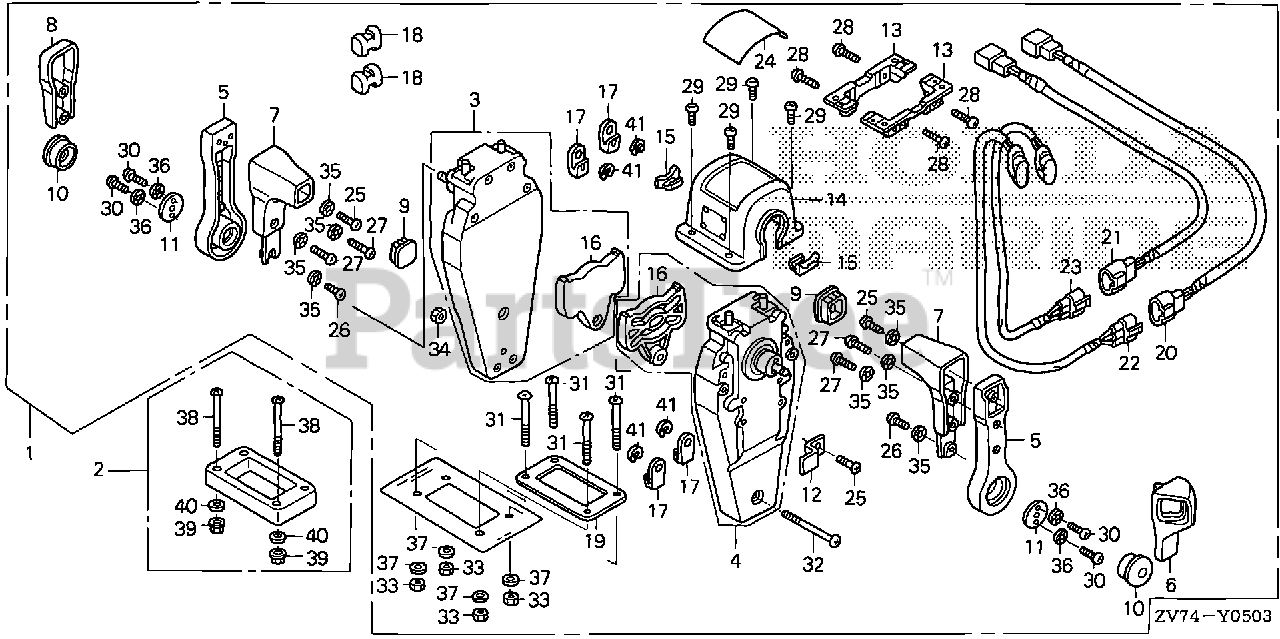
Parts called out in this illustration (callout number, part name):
1	BOX KIT, REMOTE CONTROL (TOP MOUNT DUAL)(L)
2	SPACER KIT, REMOTE CONTROL BOX (TOP MOUNT DUAL)
3	HOUSING ASSY., L. (INNER) (TOP MOUNT)
4	HOUSING ASSY., R. (INNER) (TOP MOUNT)
5	HANDLE, REMOTE CONTROL
6	COVER, R. GRIP
7	GRIP, REMOTE CONTROL HANDLE
8	COVER, DUAL GRIP
9	CAP, GRIP
10	BUTTON, THROTTLE
11	PLATE, HANDLE
12	PLATE, CABLE CLAMP
13	BRACKET, REMOTE CONTROL HOUSING
14	HOUSING, DUAL REMOTE CONTROL BOX
15	HOUSING, LEAD
16	PLATE, DWELL
17	TERMINAL, CABLE
18	SPACER, CABLE CLAMP
19	GASKET, DUAL
20	SUB-HARNESS ASSY., POWER TRIM-TILT (A)
21	SUB-HARNESS ASSY., POWER TRIM-TILT (B)
22	SWITCH ASSY., POWER TRIM-TILT (A)
23	SWITCH ASSY., POWER TRIM-TILT (B)
24	MARK, REMOTE CONTROL (DUAL)
25	SCREW, PAN (5X16)
26	SCREW, PAN (5X10)
27	SCREW, PAN (5X20)
28	SCREW, PAN (5X18)
29	SCREW, PAN (4X10)
30	SCREW, PAN (6X18)
31	SCREW, PAN (5X40)
32	SCREW, PAN (5X55)
33	NUT, HEX. (5MM)
34	NUT, HEX. (5MM)
35	WASHER, LOCK (5MM)
36	WASHER, LOCK (6MM)
37	WASHER, PLAIN (5MM)
38	SCREW, PAN (5X65)
39	NUT, HEX. (5MM)
40	WASHER, PLAIN (5MM)
41	E-RING (6MM)
